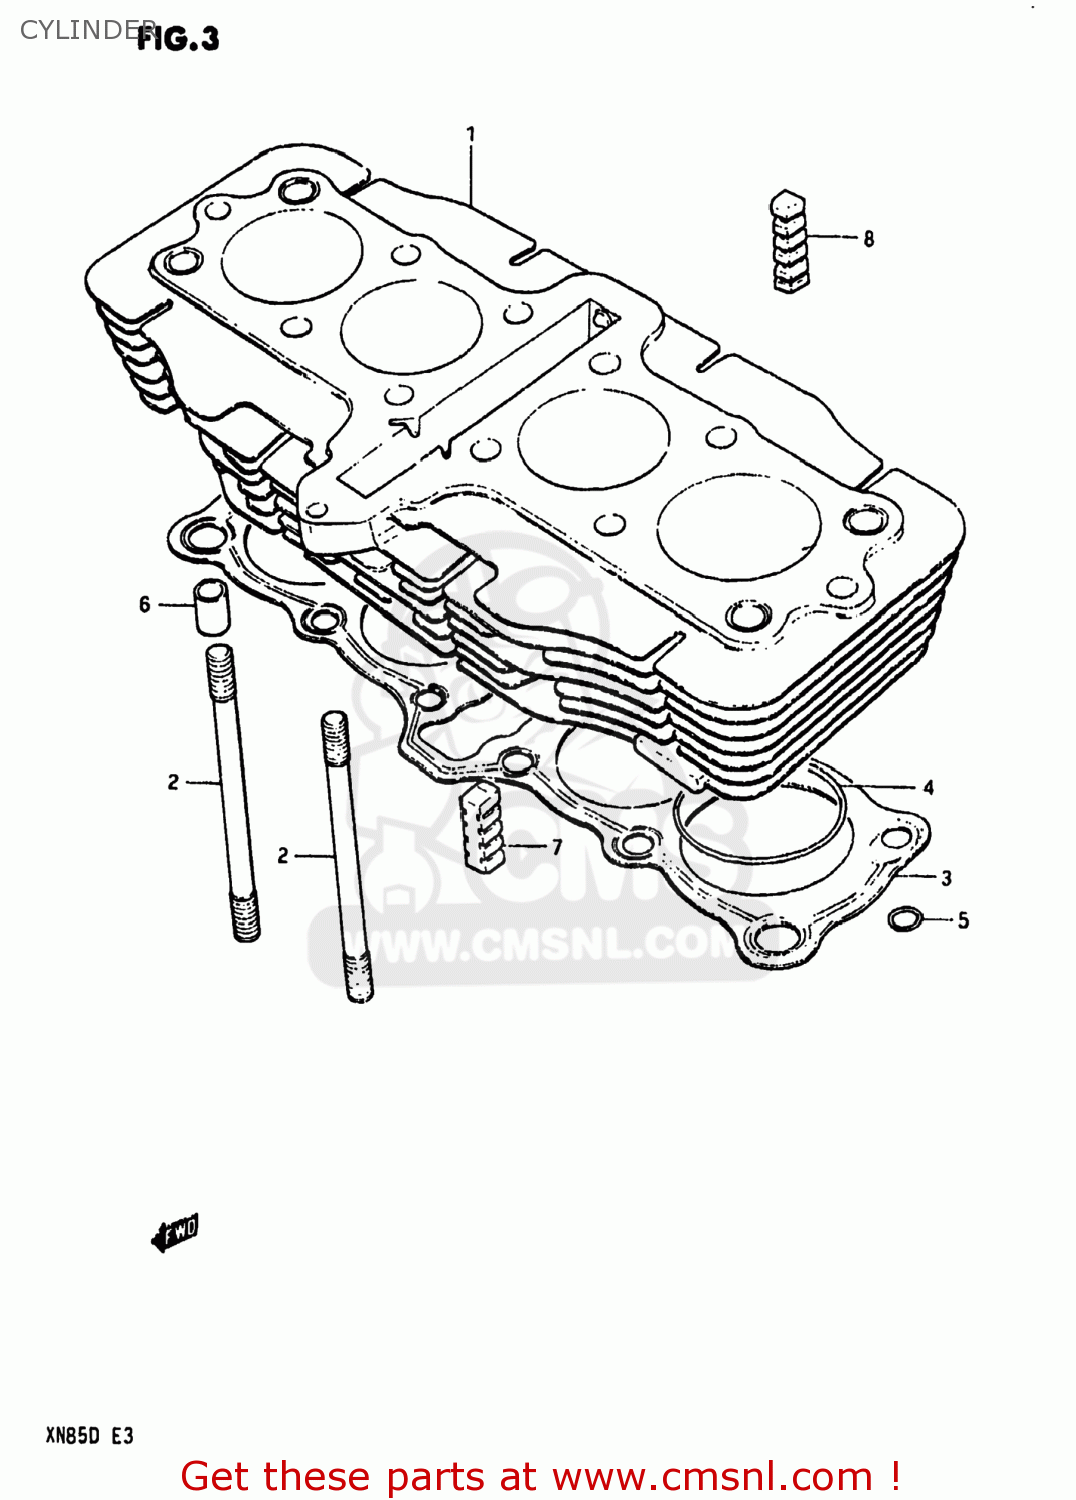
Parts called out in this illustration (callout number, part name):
1	CYLINDER
2	STUD
3	GASKET,CYLINDER
4	O RING(D:2,ID:61)
5	O RING(D:2.4,ID:12.3)
6	PIN
7	PAD,CYLINDER
8	PIN,EXHAUST VALVE
